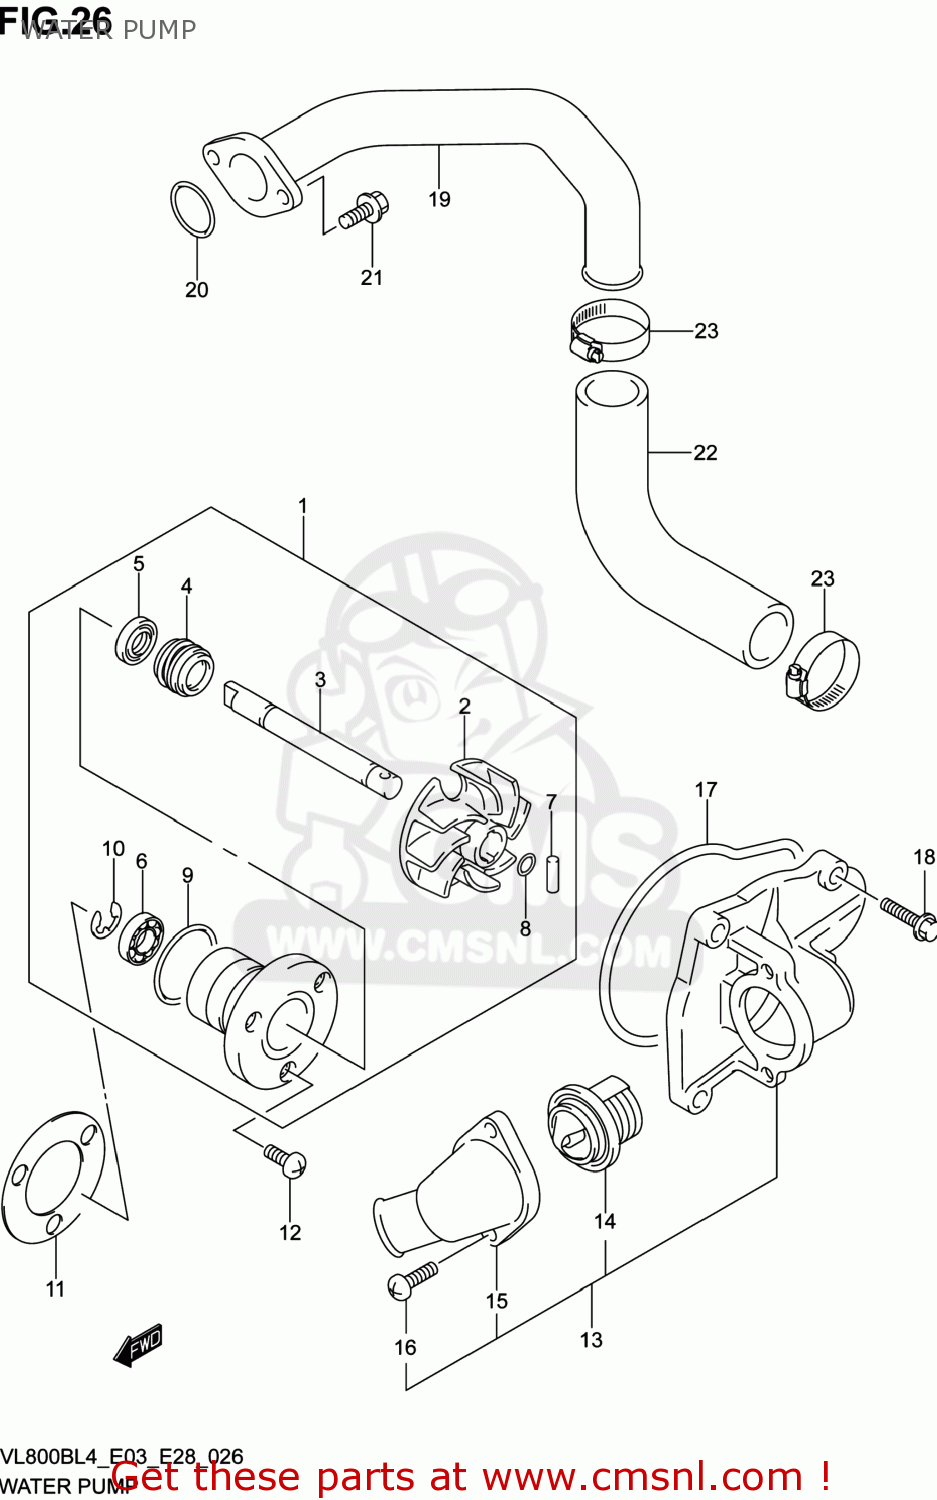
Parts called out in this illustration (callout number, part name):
1	PUMP ASSY,WATER
2	IMPELLER
3	SHAFT
4	SEAL,MECHANICAL
5	SEAL,OIL(10X21X5)
6	BEARING(10X22X6)
7	PIN
8	O RING
9	O RING
10	E RING
11	GASKET,WATER PUMP (NAS)
12	SCREW
13	CAP ASSY,WATER PUMP
14	THERMOSTAT,WATER
15	CONNECTOR
16	SCREW
17	O RING,WATER PUMP CAP
18	BOLT
19	PIPE,CYLINDER INLET
20	O RING(D:2.3,ID:24.4)
21	BOLT
22	HOSE,WATER PUMP OUTLET
23	CLAMP
